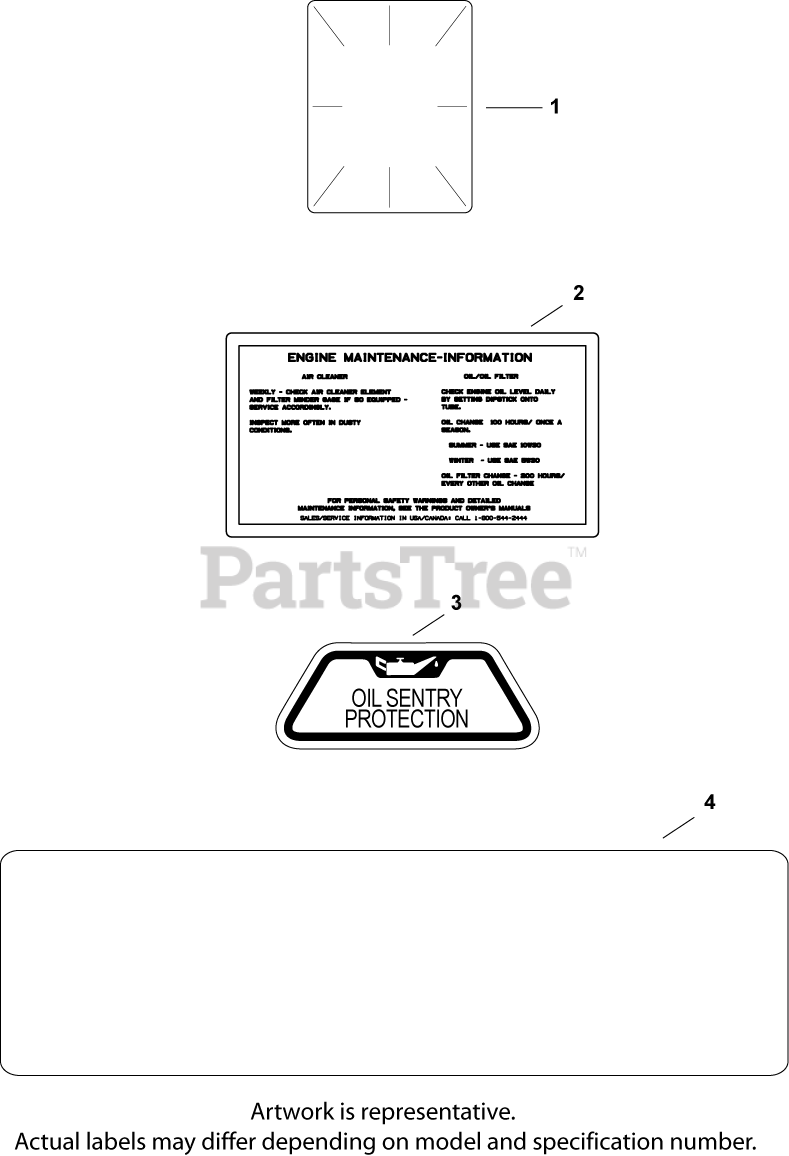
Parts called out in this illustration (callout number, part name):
1	DECAL, CLEAR LAMINATE USE 25 113 70-S
2	DECAL, AIR CLEANER - (#DSC)
3	DECAL, OIL SENTRY - (#DSC)
4	DECAL, 20 HP
